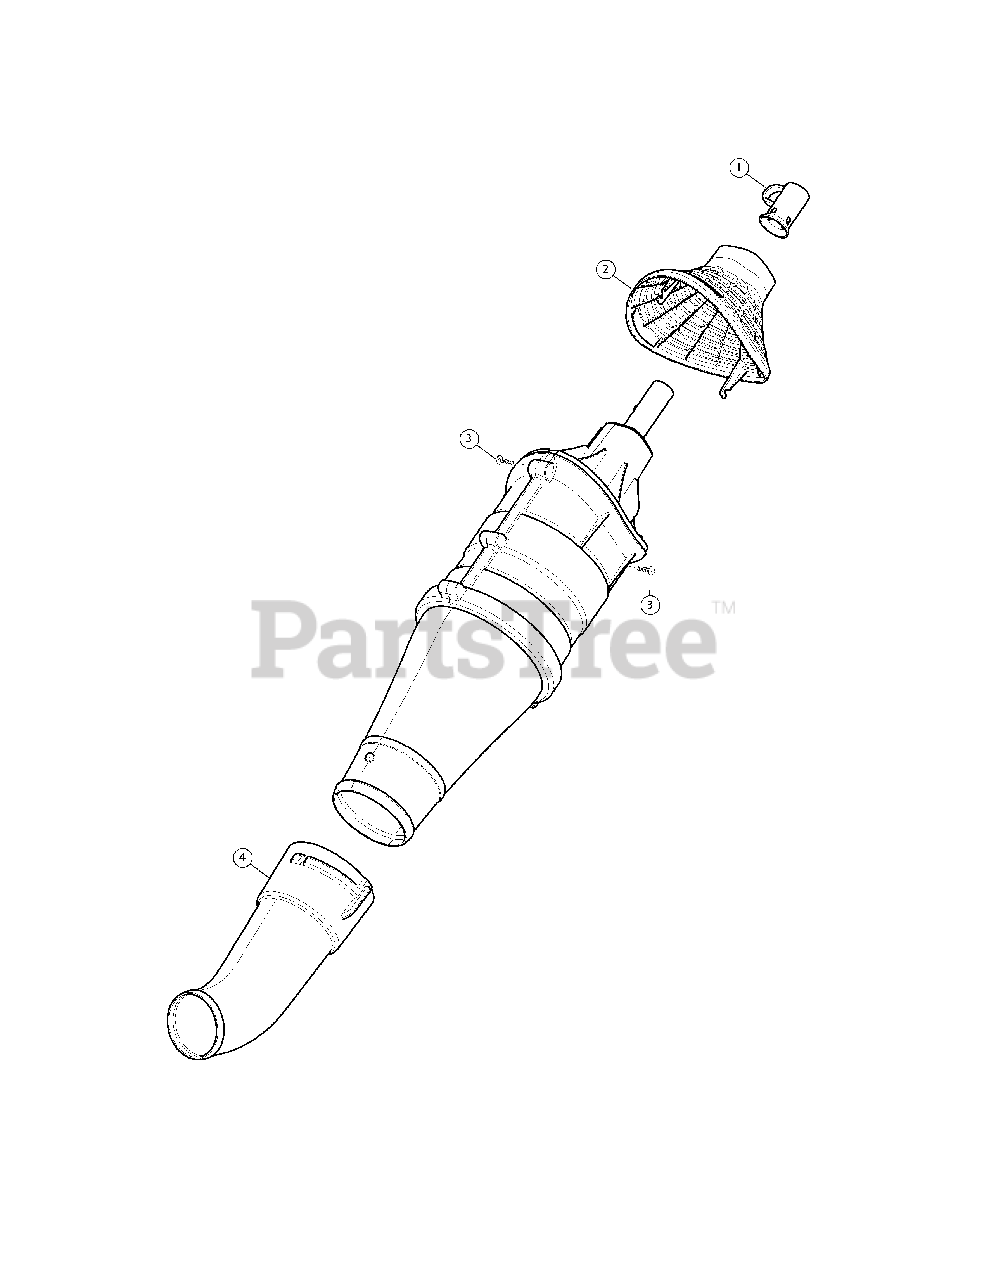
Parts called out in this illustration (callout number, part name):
2	Blower Intake Housing
3	Screw
4	Blower Nozzle
